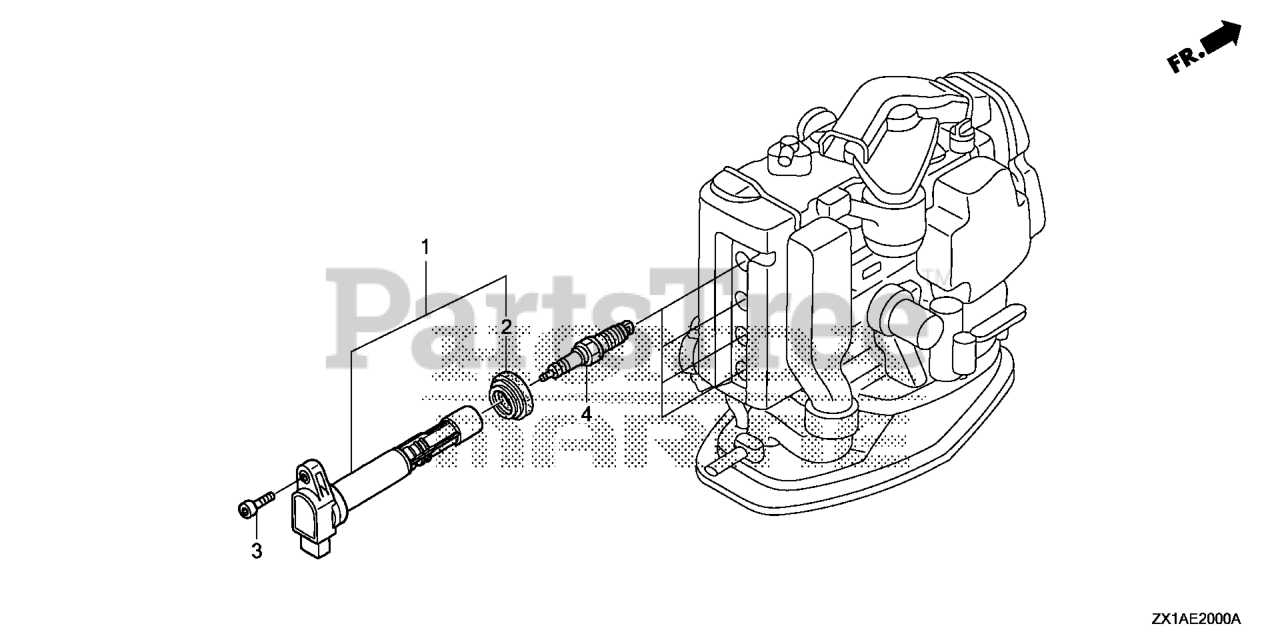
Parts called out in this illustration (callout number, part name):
1	COIL, PLUG HOLE
2	SEAL, PLUG HOLE
3	BOLT, SOCKET (6X25)
4	SPARK PLUG (KJ20DR-M11) (DENSO)
4	SPARK PLUG (SKJ20DR-M11) (DENSO)
4	SPARK PLUG (ZFR6K-11) (NGK)
4	SPARK PLUG (IZFR6K-11) (NGK)
